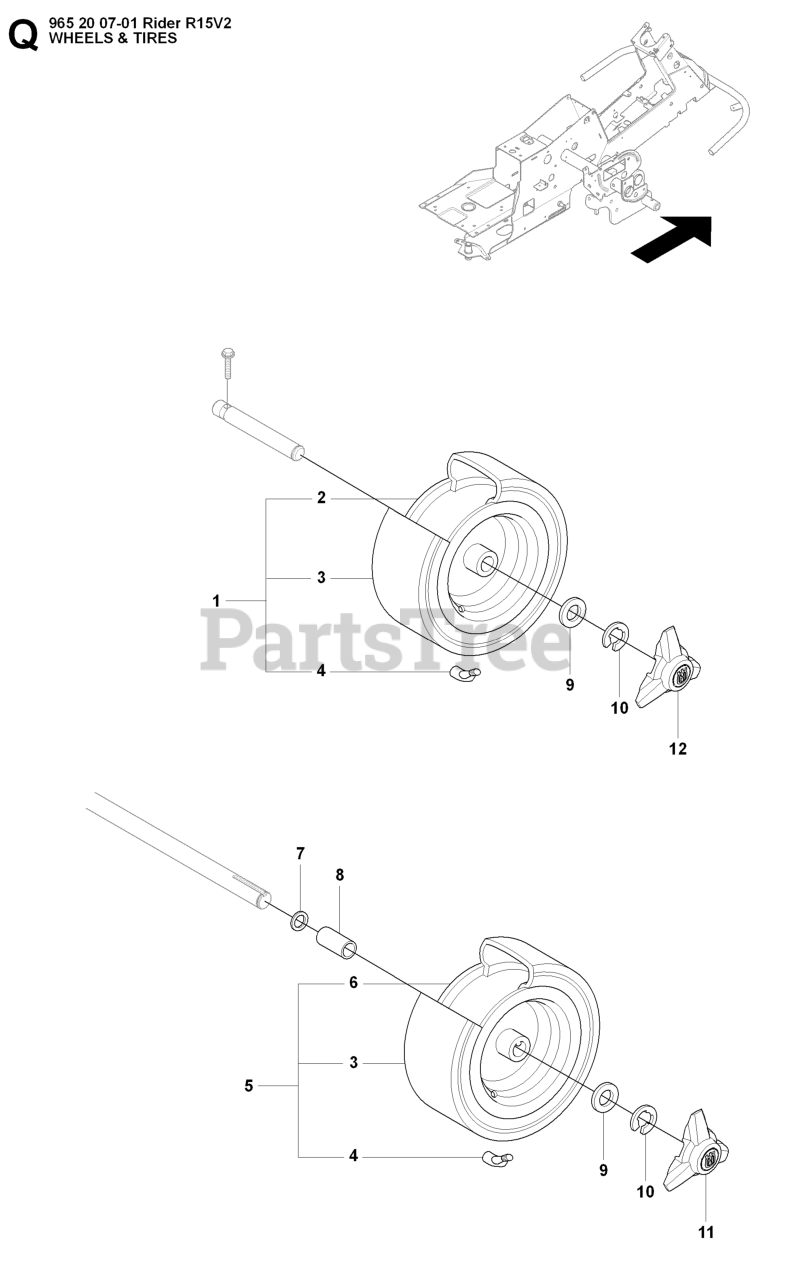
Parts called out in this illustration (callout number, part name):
5	WHEEL
6	RP RIM
10	SPACE SLEEVE
12	RETAINING RING
